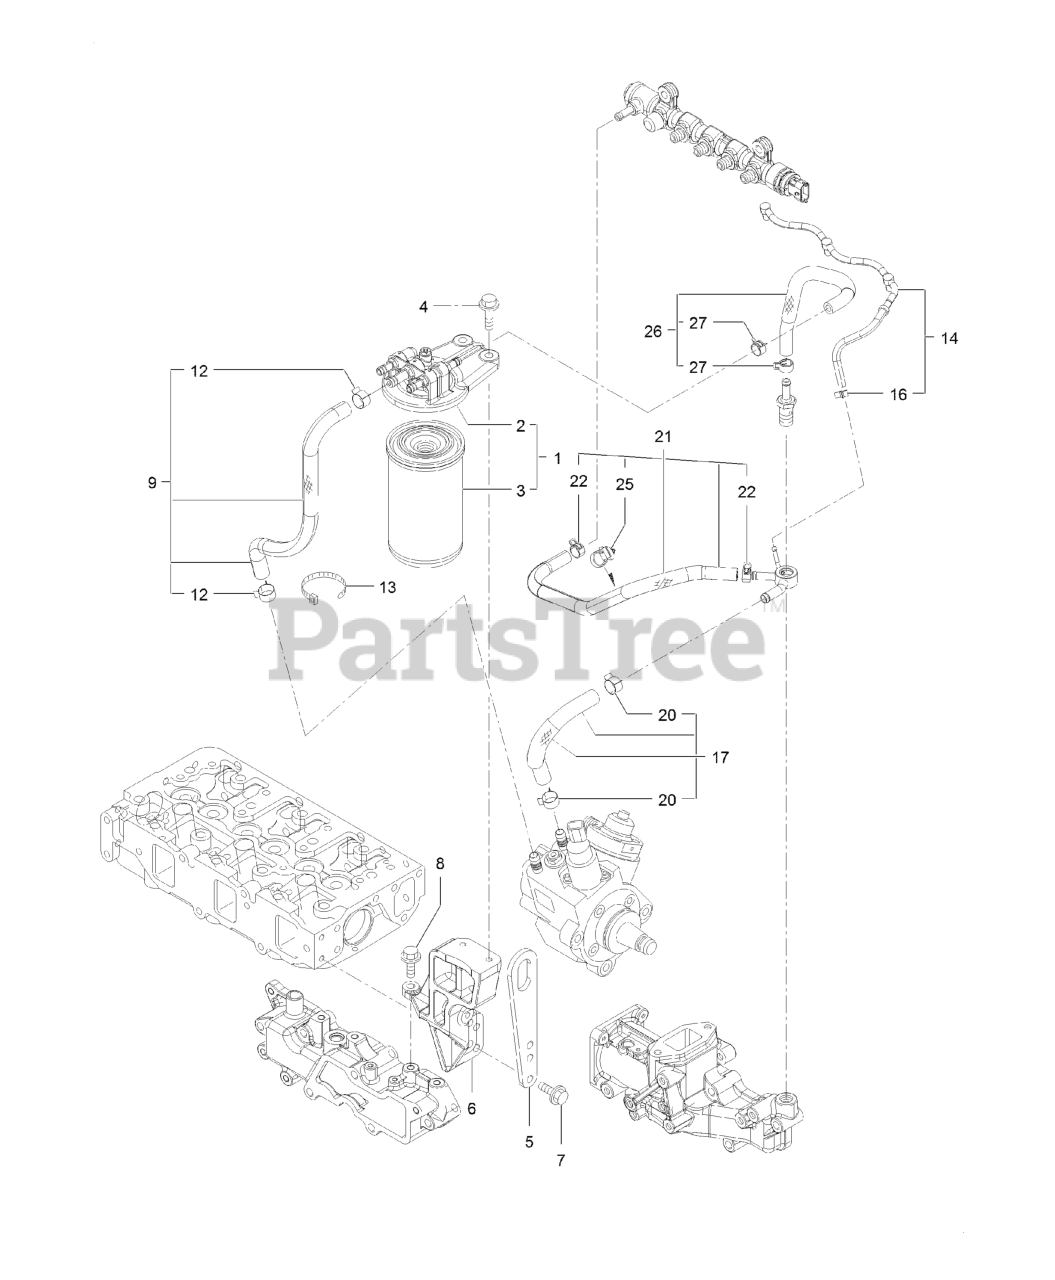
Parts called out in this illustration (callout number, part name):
1	FUEL/OIL FILTER ASM
2	FUEL/OIL FILTER BRACKET A
3	FILTER-FUEL/OIL
6	FILTER BRACKET ASM
9	FUEL PIPE ASM
12	CLAMP-HOSE
14	PIPE ASM-FO RETURN
16	CLAMP-HOSE
17	FUEL PIPE ASM
20	CLAMP-HOSE
21	FUEL PIPE ASM
22	CLIP-HOSE
25	BAND-CLIP
26	FUEL PIPE ASM
27	CLIP-HOSE
